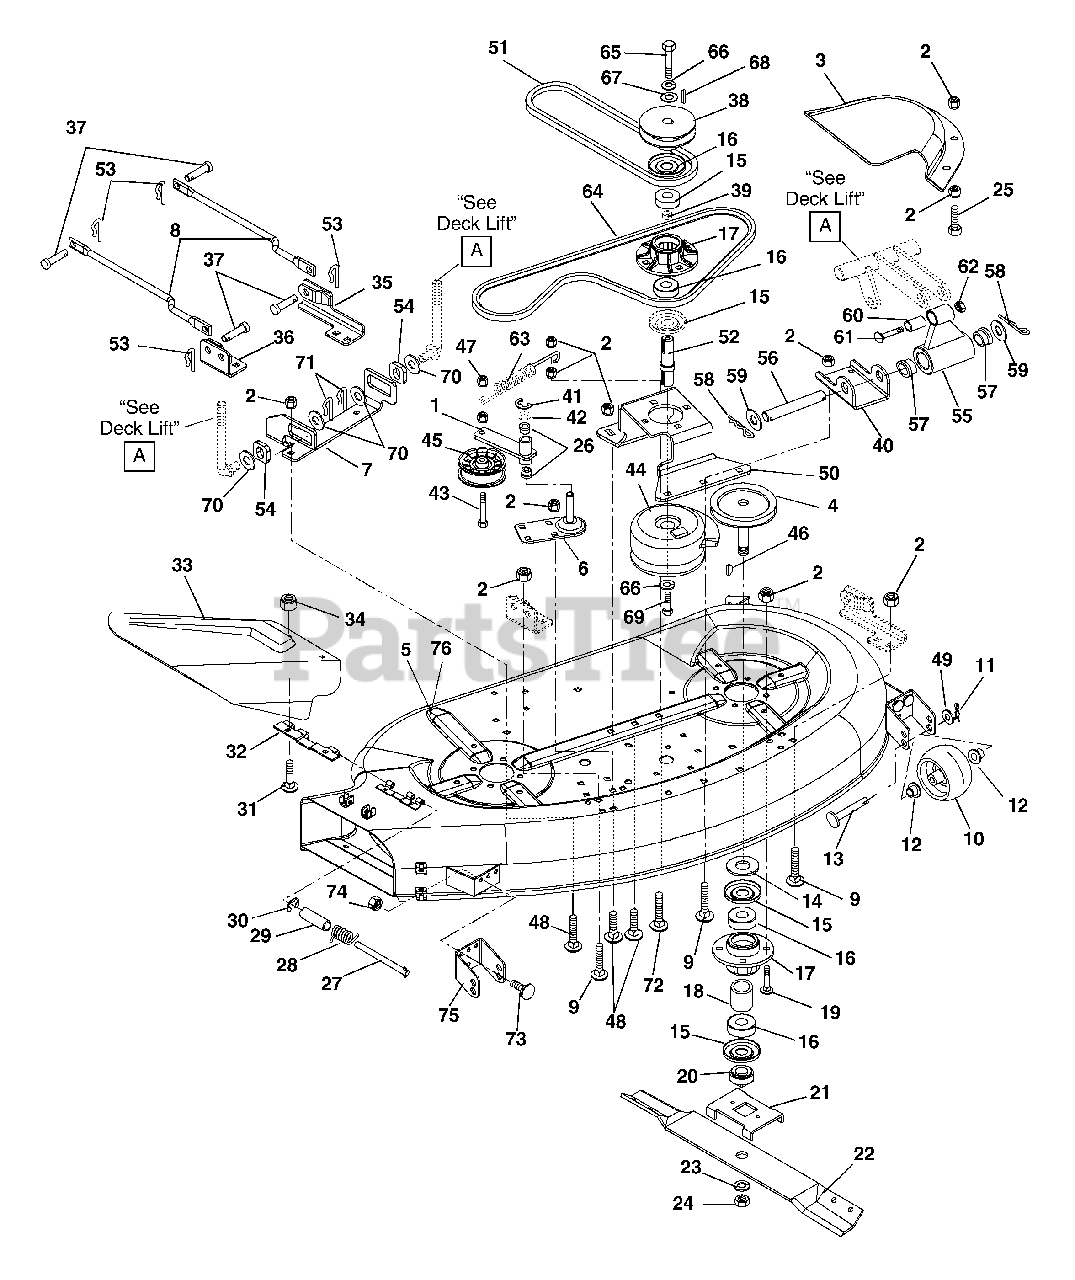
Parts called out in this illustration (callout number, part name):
1	WLDMT-IDLER
2	NUT-LK-TOP-FLG .38-16 BLKZC
3	COVER, 40" DECK SHEAVE
4	L. SPINDLE SHEAVE
4	R. SPINDLE SHEAVE
5	WLDMT - 40" DECK RAW
6	BKT-IDLER MOUNT
7	BRKT, REAR HANGER (40" DECK)
8	LINK-STABILIZER 40" DECK BLK
9	BLT-RDHDSQNK .38-16X1.00 G5BZ
11	PIN-HAIR INT .08X.18X1.18 YWZC
12	BSHG-FLG .372X.500X.312X.625NY
13	PIN-CLEV .371X3.25 YWZC
14	WSHR-FL-STL .755X1.25X.125 YZ
15	BEARING SLINGER
16	BRG-BALL .750X1.781X.61
17	SPINDLE HOUSING
18	SPACER .753X1.000X1.140
19	@BLT-RDHDSQNK .38-16X1.00 G5YZ
20	RETAINER HUB
21	BLADE TRAY 48
23	@WSHR-LK .75X.188 REG YWZC
24	NUT-JAM .75-10 YWZC
25	@BLT-HEX .38-16X1.00 GR5 YWZC
26	BSHG-FLG.500X.625X.312X.750NY
28	SG-TORS .095X.50X 1.0
29	BSHG-SLV .334 X .502 X 1.437
30	RG-RTNG-EXT .312X.025
31	BLT-RDHDSQSHNK.25-20X.50 YWZC
32	HINGE PLATE
33	40IN. CHUTE DEFLECTOR
34	NUT-LK-FLG .250-20 PL BLK
35	BKT-DECK LINK (LH)
36	WLDMT DECK LINK BKT (RH)
37	PIN-CLEV .494X1.00 BLKZC
38	PULLEY, 40" DECK INPUT
39	SPACER .753X1.000X1.140
40	BRKT, FRONT HANGER
41	RG-RTNG-EXT .500X.042 (E)
42	WSHR-FL-STL .505X.880X.072 YWZ
43	@BLT-HEX .38-16X2.25 GR5 YWZC
44	ELECTRIC CLUTCH/BRAKE (3.4AMP)
45	IDLER-FLAT 3.00X.38
46	KEY-WDRF .188X.625X.31 SAE9MOD
47	@NUT-SPNLK-FLG .375-16 YWZC
48	BLT-RDHDSQNK .38-16X.75 G5BZ
49	BLT-RDHDSQNK .31-18X1.0 SHTYZ
50	BKT SPINDLE HSG MOUNT
51	V-BELT, HA-WRAPPED
52	SHAFT, 40" DECK INPUT
53	CLIP, SPRING
54	SLIDER, HANGER BRKT
55	LINK, FRONT LIFT (40" DECK)
56	PIVOT, FRONT LIFT LOWER
57	BUSHING-1"X.75"X1"
58	PIN, HAIR #6
59	WSHR-FL-STL .700X1.47X.134 YWZ
60	BSHG-SLV .500X.750X1.560
61	BLT-RDHDSQSHNK .50-13X2.75 YZ
62	NUT-LK-CTR-JAM .50-13 YWZC(ND)
63	SG-TENS .095X.500X5.5 WLD60 YZ
64	V-BELT, HA-RAW EDGE
65	BLT-HEX .38-16X1.00 YZ GR8
66	WSHR-LK .375X.115 HVY YWZC
67	WSHR-FL-STL .406X1.375X.135 YZ
68	KEY-SQ .187 X .50 X .187
69	BLT-HEX .38-24X2.0 YWZC
70	WSHR-FL-STL .518X2.0X.105 YWZC
71	PIN, HAIR, EXT - #16 YWZC
72	@BLT-RDHDSQNK .38-16X2.00 G5YZ
73	@BLT-RHDSSQNK .31-18X.62 G5YZ
74	@NUT-SPNLK-FLG .312-18 YWZC
75	ROLLER CLEVIS
76	KIT, 40" DECK ASSY SERVICE
